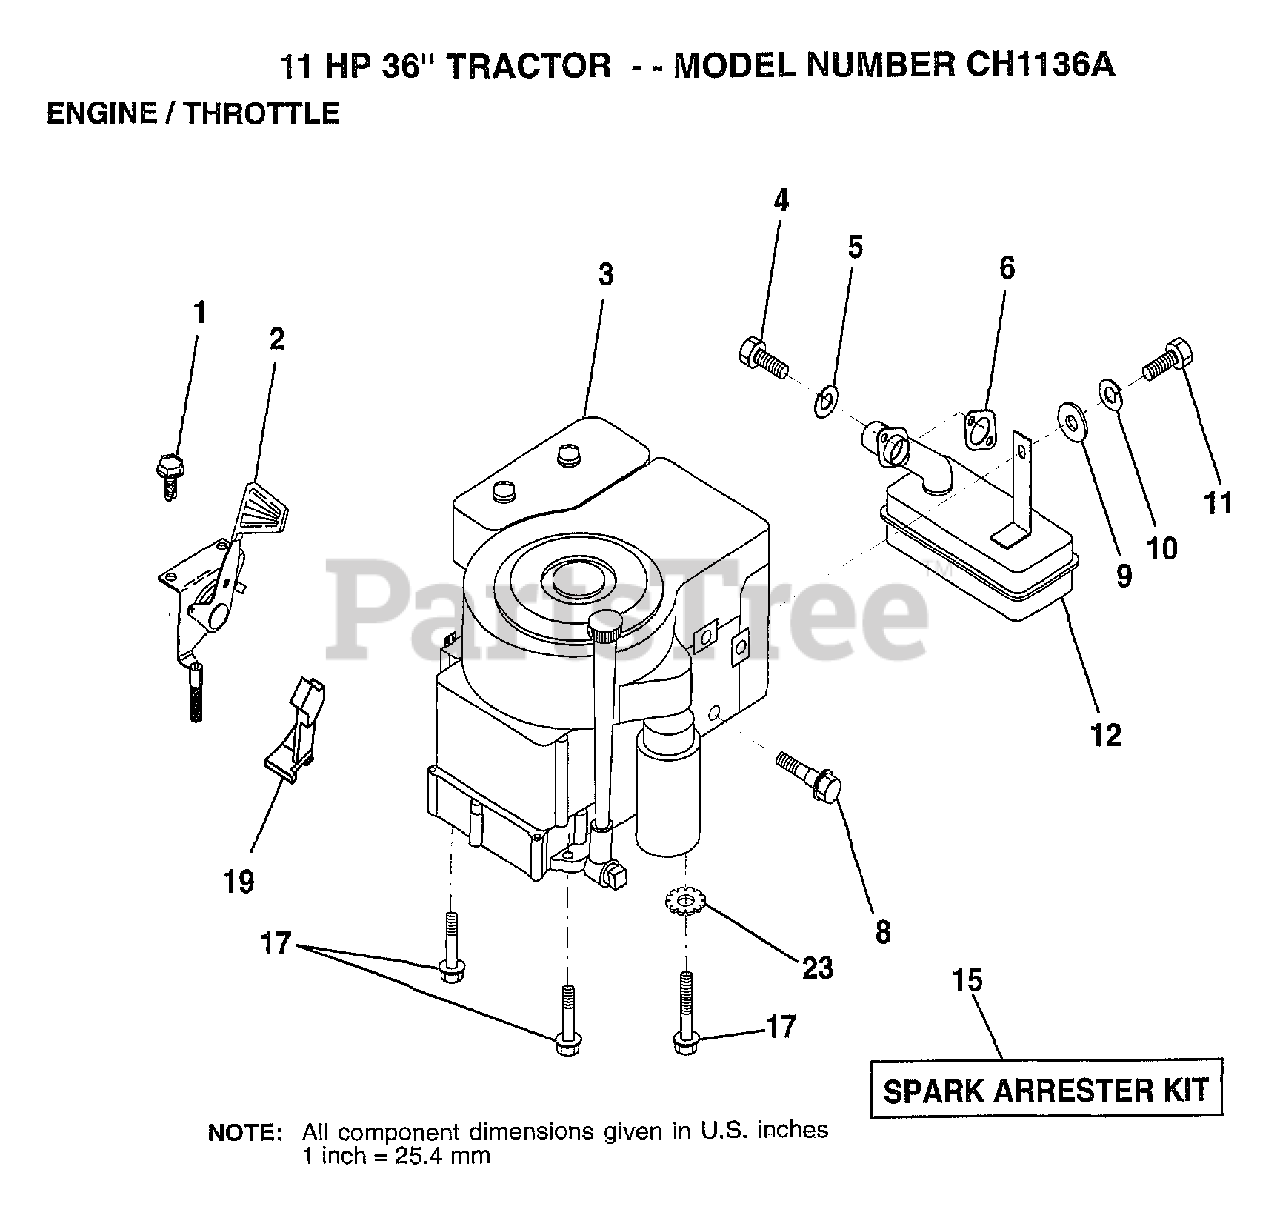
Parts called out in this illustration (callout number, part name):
1	SCREW.1/4-20X1/2
4	SCREW
5	LOCKWASHER
8	BOLT T
10	LOCKWASHER
11	BOLT
12	MUFFLER
17	SCREW LT
19	"STOP,DASH THROTT"
23	LOCKWASHER
